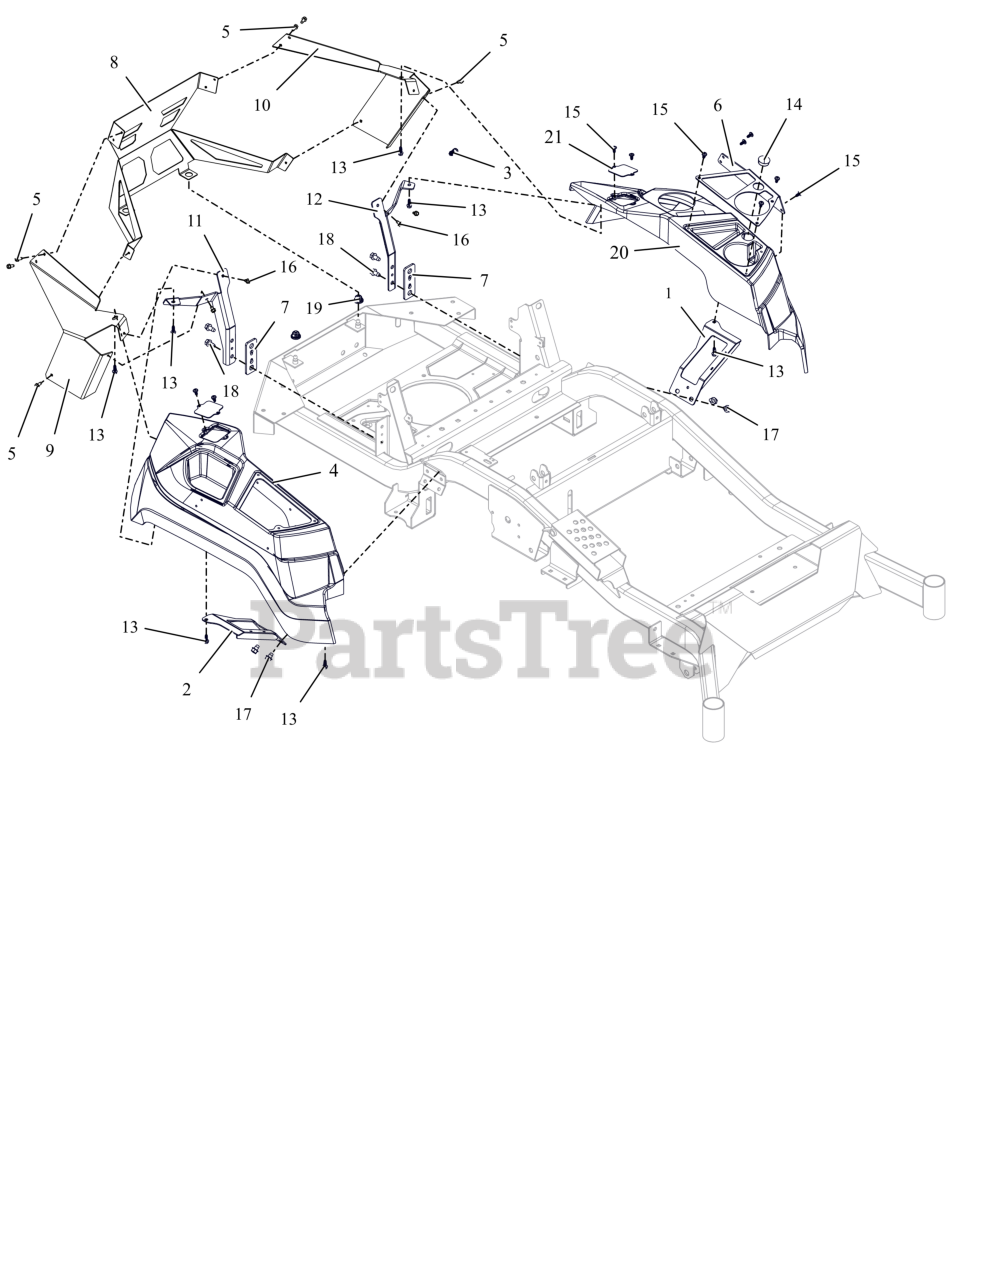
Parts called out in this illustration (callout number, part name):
1	WLDMT, LH FENDER MOUNT
2	WLDMT, RH FENDER MOUNT
3	CLIP, CABLE GUIDE
4	FENDER, RH APEX - 2017
5	SCR-TAP .25X.50 HWH ZB500
6	PLATE-APEX CUP HLDR W/USB(ORG)
7	PLATE, CONTROL PANEL SPACER
8	GUARD, ENGINE (BLACK)
9	PANEL, RH REAR FENDER MOUNT (ORANGE)
10	PANEL, LH REAR FENDER MOUNT (ORANGE)
11	BRKT, RH FENDER MTG (ORANGE)
12	BRKT, LH FENDER MOUNT (ORANGE)
13	SCR, PLASTITE .25-10X.75 ZCC
14	PLUG, HOLE 1.125 DOMED
15	SCR-PAN .25-15X.50 6L H/LZB500
16	SCR,TAP .25-20X.375 HWH TR ZCC
17	SCR,TAP .375-16X.50 HWH TR ZCC
18	SCR,TAP .375-16X.75 HWH TR ZCC
19	GROMMET, 10MM BOLLHOFF
20	FENDER, LH APEX
21	PLATE, ROPS HOLE-HD
